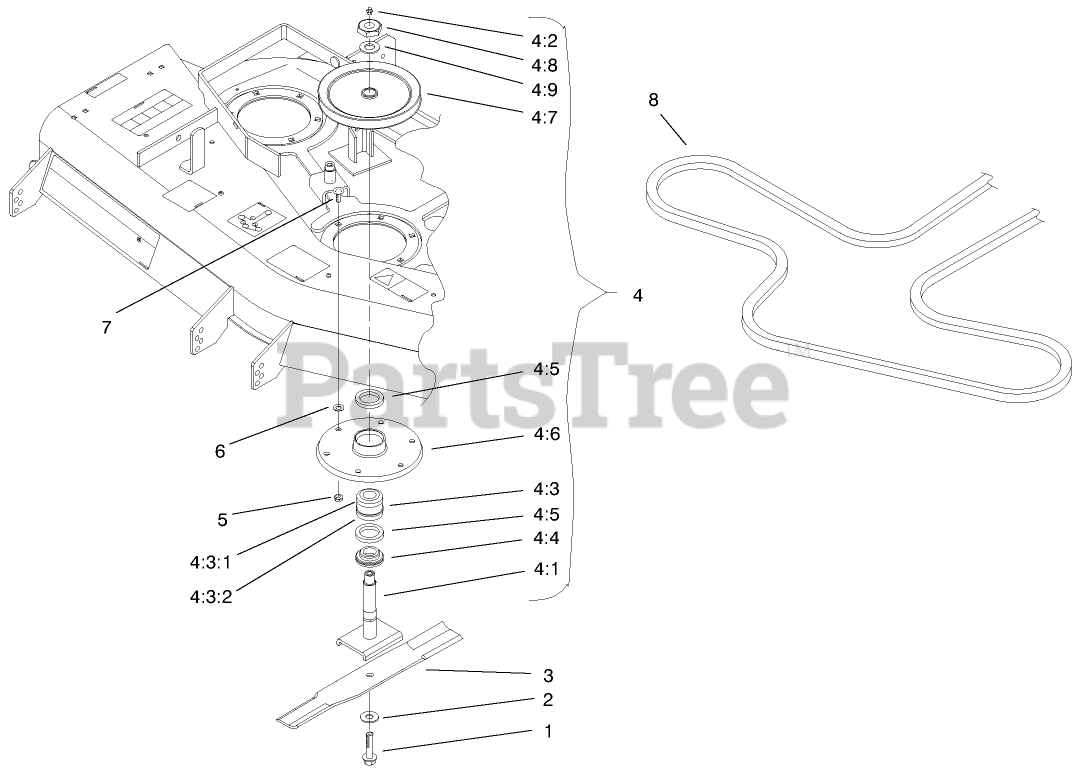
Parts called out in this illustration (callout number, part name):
1	BOLT-BLADE
2	Washer-Flat
3	BLADE-SAIL, EXTRA HIGH
4	Spindle Housing ASM
4:1	Shaft-Spindle
4:2	FITTING-GREASE
4:3	BEARING ASM
4:3:1	BEARING ASM
4:3:2	SPACER-SET, MATCHED
4:4	SPACER
4:5	SEAL-OIL
4:6	HOUSING-SPINDLE
4:7	Pulley & Hub
4:8	NUT-HEX
4:9	WASHER
5	NUT-HF
6	WASHER-FLAT
7	SCREW-CARR
8	BELT-DECK (52)
